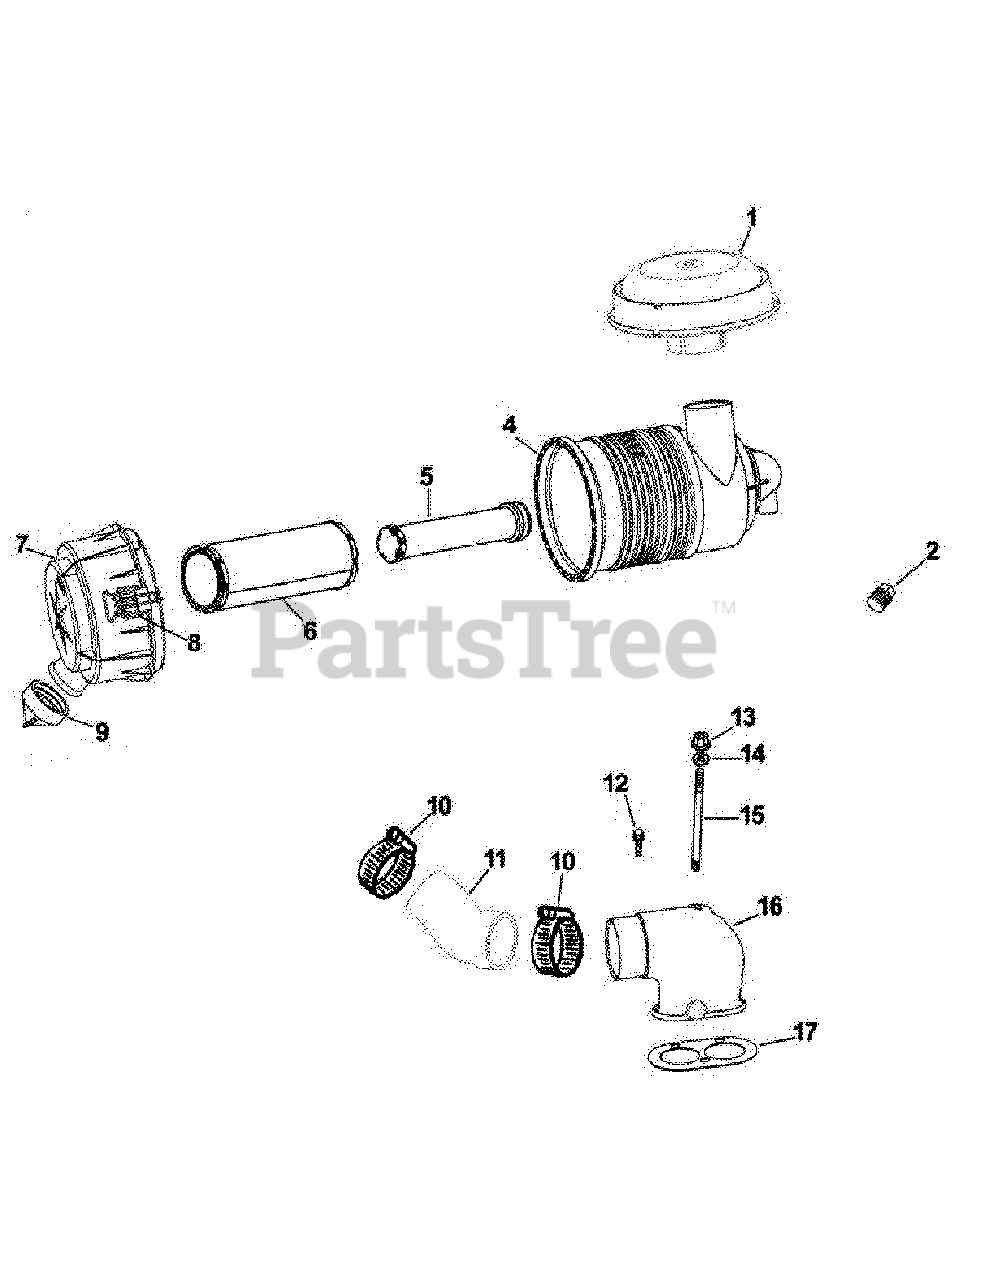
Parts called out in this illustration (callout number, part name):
5	Air Cleaner Element (Safety)
6	Air Cleaner Element (Primary)
7	Cover Assembly
8	Clip
9	Dust Ejector Valve
11	Air Cleaner Hose
12	Hex Flange Screw
13	Hex Flange Nut
14	Copper Washer
15	Stud
16	Air Cleaner Adapter
17	Air Cleaner Base Gasket
